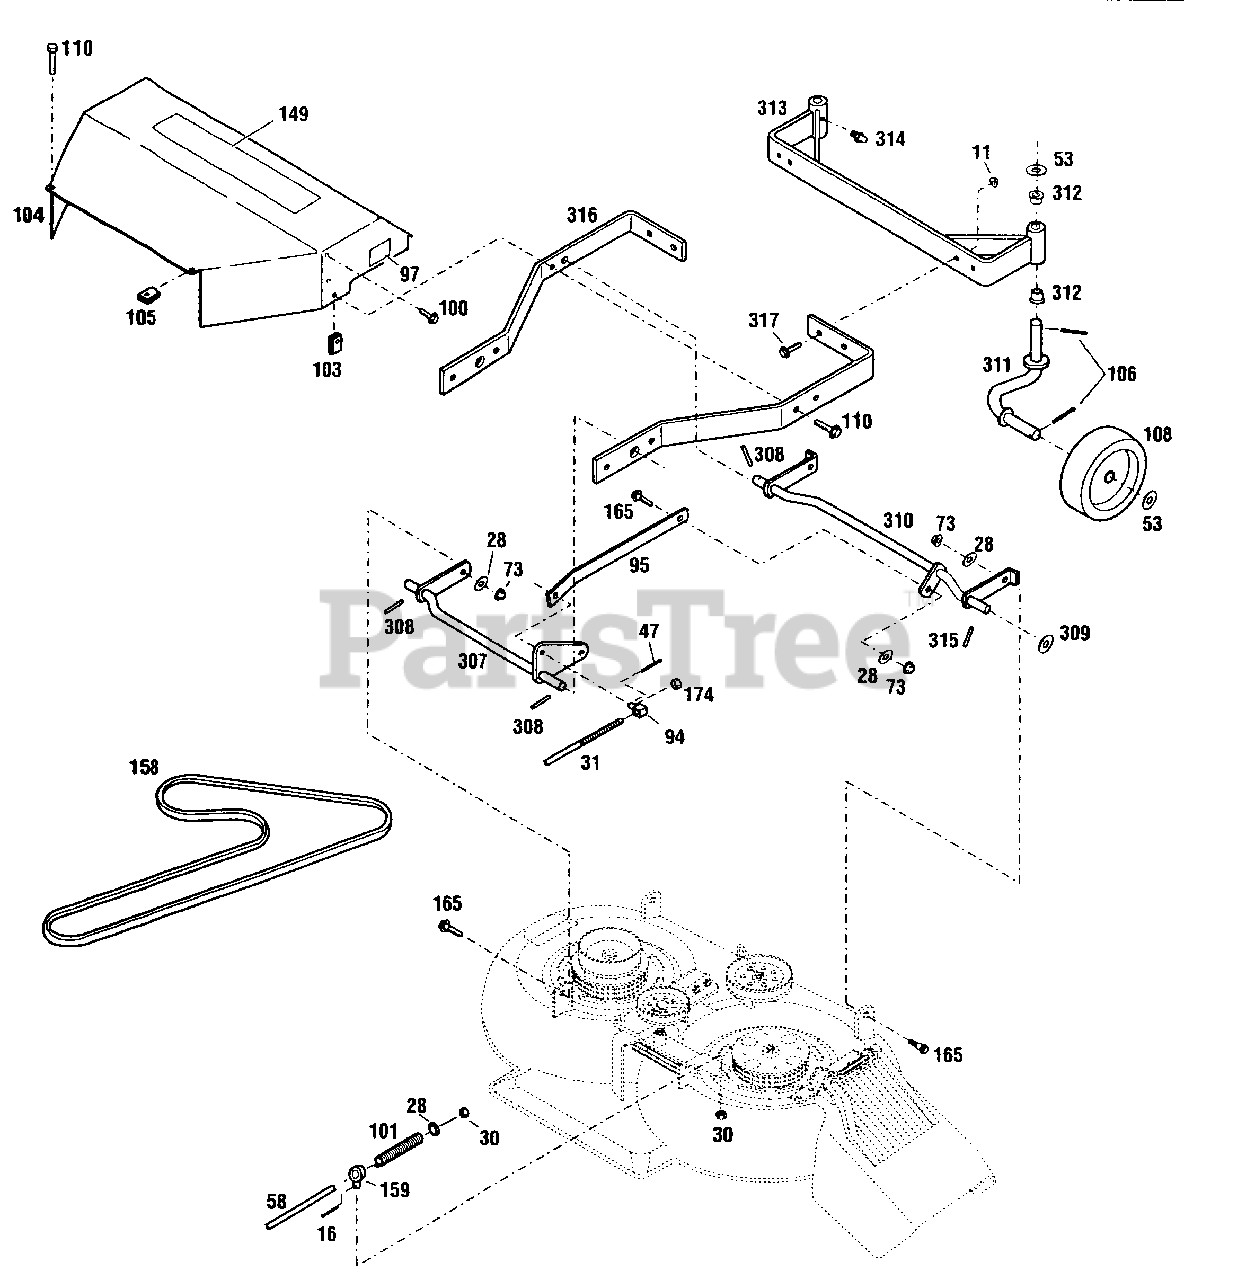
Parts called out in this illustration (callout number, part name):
11	Flange Locknut, 3/8-16
16	Cotter Pin, 3/32 x 5/8
28	Flat Washer, 3/8
30	Locknut, 3/8-16
31	Lift Crank
47	Cotter Pin
53	Special Washer
58	Lower Blade Rod
73	Flange Locknut, 3/8-16
94	Pivot Block
95	Leveler Bar
97	Cutting Height Decal
100	Tap Screw, #8 x 3/8
101	Compression Spring
103	Speed Nut, 5/16-18
104	Belt Guard
105	Speed Nut, 5/16-18
106	Cotter Pin
108	Gage Wheel
110	Flange Lock Screw, 5/16 x 3/4
149	Logo Decal
165	Shoulder Bolt
174	Toplock Nut
307	Rear Lift Assembly
308	Roll Pin, 1/4 x 1
309	Flat Washer, 5/8
310	Front Lift Assembly
311	Spindle Assembly
312	Flange Bearing
313	Gage Support
314	Grease Fitting
315	Drive Pin, 1/4 x 3
316	Mower Support
317	Whizlock Screw, 3/8-16 x 1
